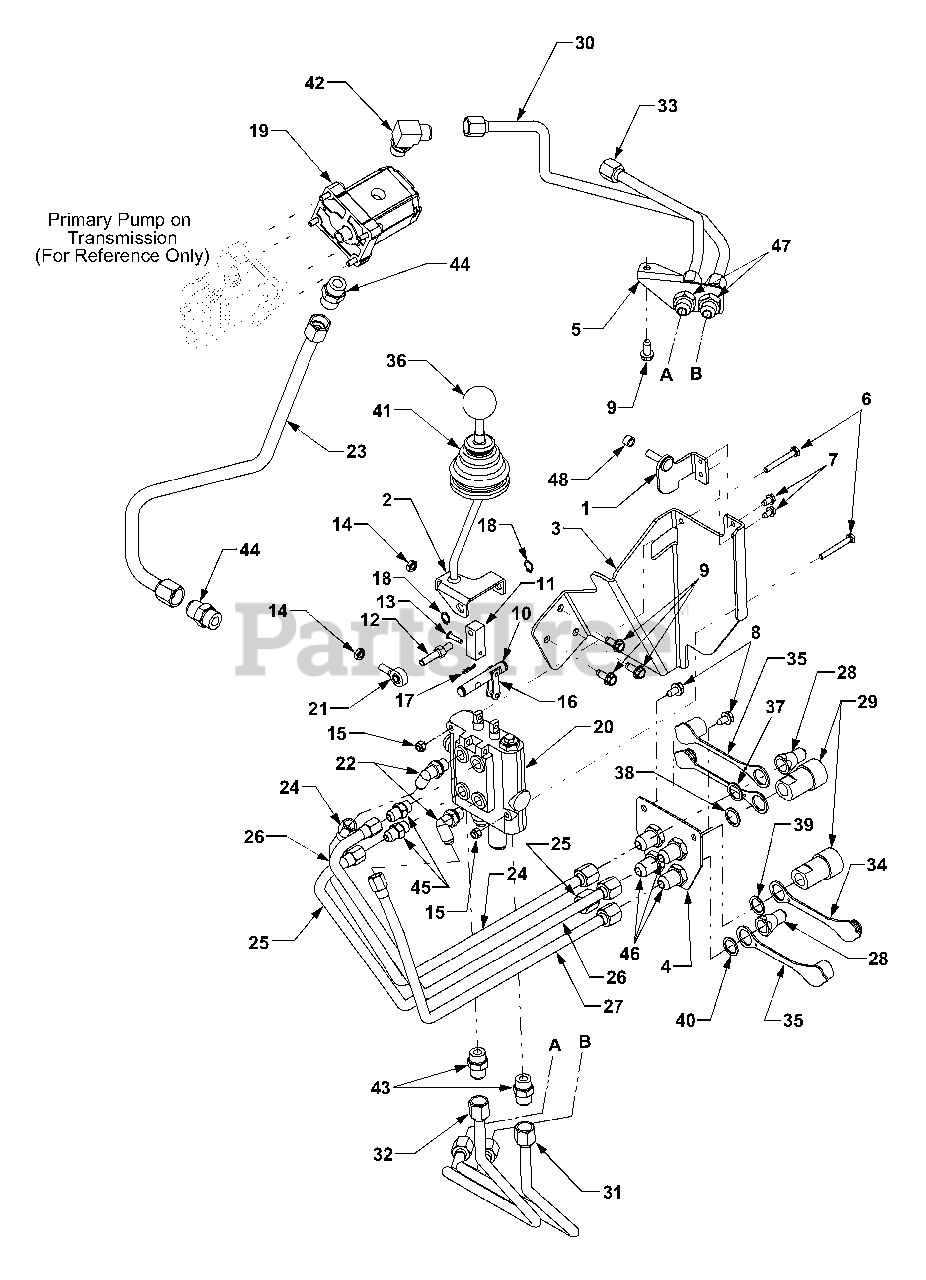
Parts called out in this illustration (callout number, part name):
1	Pivot Bracket Assembly
2	Valve Handle Assembly
3	Loader Valve Mount Bracket
4	Fitting Mount Plate
5	Rear Fitting Mount Plate
6	Hex Screw, 1/4-20, 2.00, Gr5
7	Hex Wash. Hd. Tapp Screw 1/4-20 x .50
8	Hex Wash. Hd. Tapp Screw 5/16-18 x .625
9	Hex Wash. Hd. Tapp Screw 5/16-18 x .75
10	Valve Pivot Shaft
11	Valve Spool Link
12	Ball Joint Pivot Stud
13	Clevis Pin, .199 x .8125
14	Jam Nut, 5/16-24, Gr2
15	Hex Lock Nut, 1/4-20, Gr8, Nylon
16	Chain Link
17	Internal Cotter Pin
18	Snap Ring, .5
19	Auxiliary Hydraulic Pump
20	Loader Control Valve
21	Ball Joint, .3125 Id x 5/16-24
22	Fitting, 90° 6-6 Orb
23	Tube, Tandum Pump Suction
24	Tube, Hydraulic - Bucket Rollback
25	Tube, Hydraulic - Bucket Dump
26	Tube, Hydraulic - Boom Lift
27	Tube, Hydraulic - Boom Lower
28	Coupling, Male Hydraulic, 3/8-18
29	Coupling, Female Hydr. 3/8-18
30	Tube, Auxiliary Pump Pressure
31	Tube, Valve Pressure
32	Tube, Valve Return
33	Tube, Valve Return
34	Plug, Hydraulic Coupler - Male
35	Plug, Hydraulic Coupler - Female
36	Knob, 1.625 Dia x 3/8-16 Thd
37	Washer, Indicator - Red
38	Washer, Indicator - Yellow
39	Washer, Indicator - Green
40	Washer, Indicator - Blue
41	Joystick Boot
42	Fitting, 90° -8 Orb
43	Fitting, Straight -8 Orb
44	Fitting, Straight
45	Fitting, Straight - 6 Orb
46	Fitting, Bulkhead 3/4-16 x 3/8-18
47	Fitting, Bulkhead 3/4-16 x 3/4-16
48	Spacer, .34 ID x .5 OD x .31
